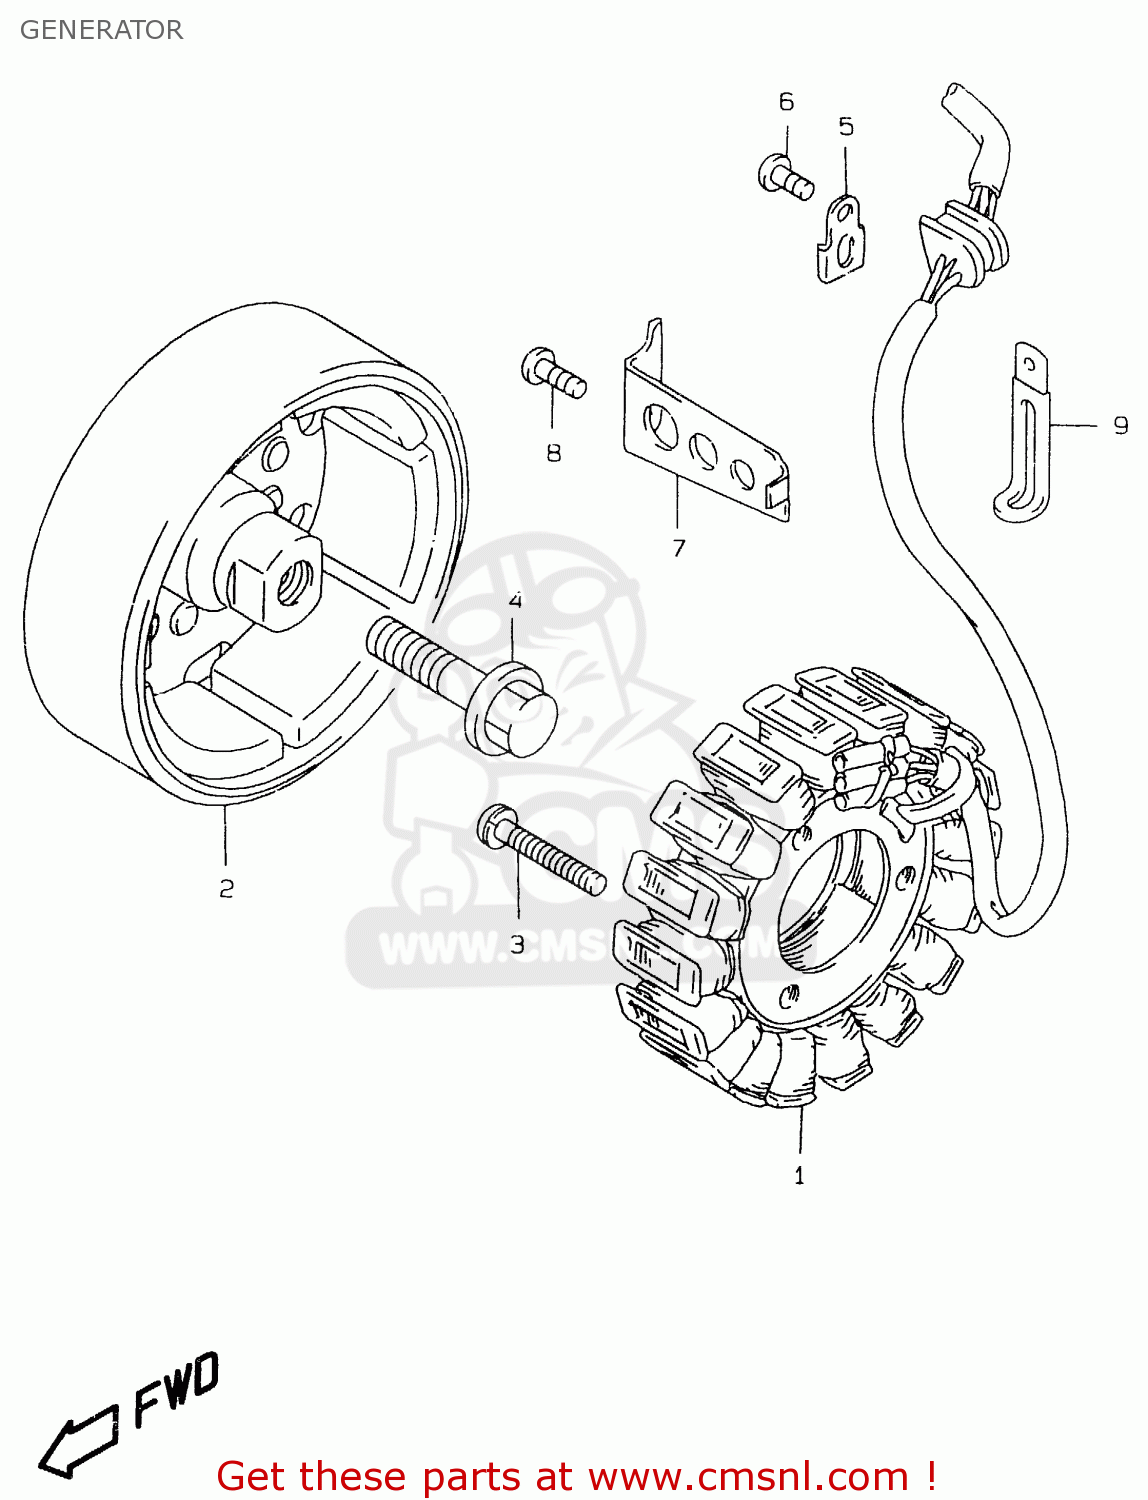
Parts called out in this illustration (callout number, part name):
1	STARTER ASSY
2	ROTOR ASSY
3	SCREW
4	BOLT(12X40)
5	CLAMP,GENERATOR LEAD WIRE
6	SCREW
7	CLAMP,GENERATOR LEAD WIRE
8	SCREW
9	CLAMP(L:65)
